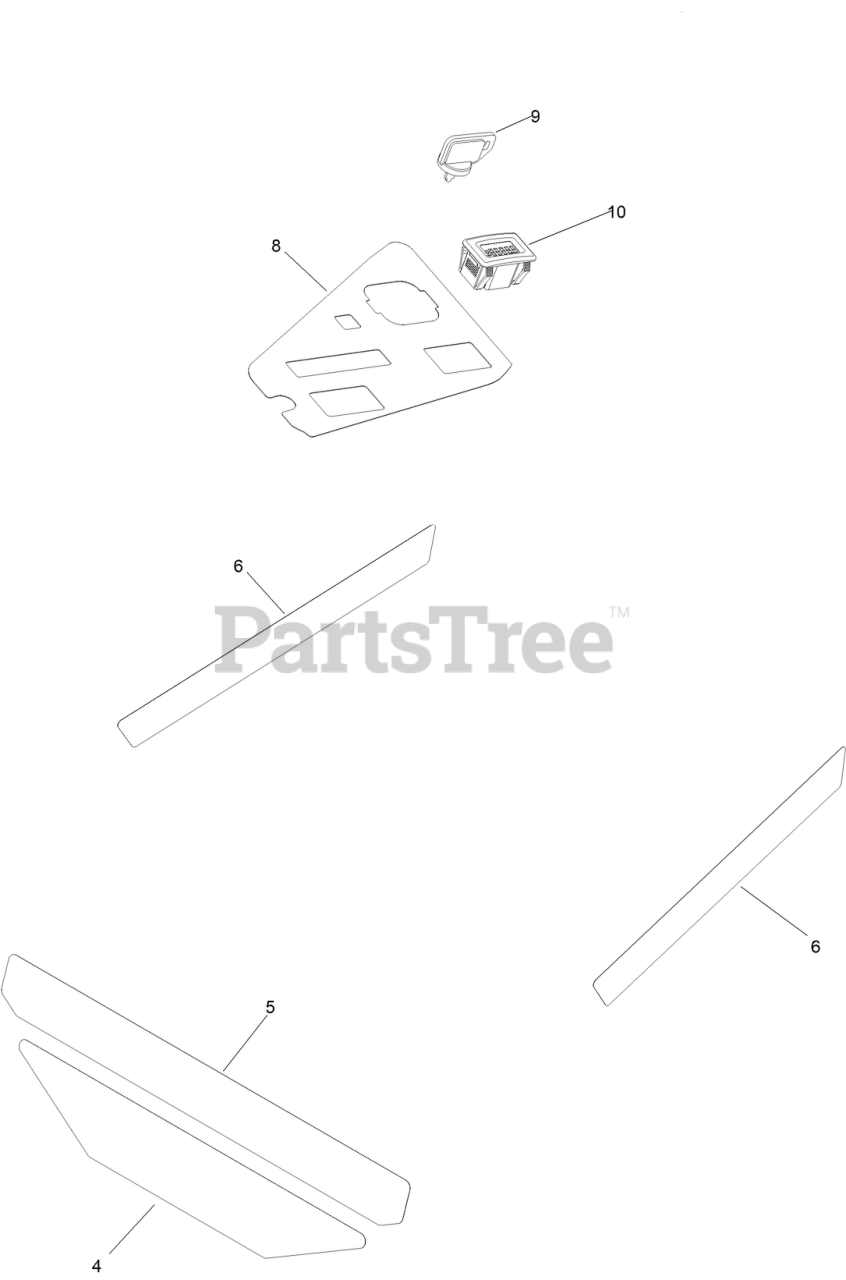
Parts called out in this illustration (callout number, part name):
4	DECAL MX5400T
5	DECAL-TIMECUTTER MAX, SEAT
6	DECAL-TIMECUTTER MAX
8	DECAL - CONTROL PANEL
9	KEY-IGNITION
10	HOUR METER
